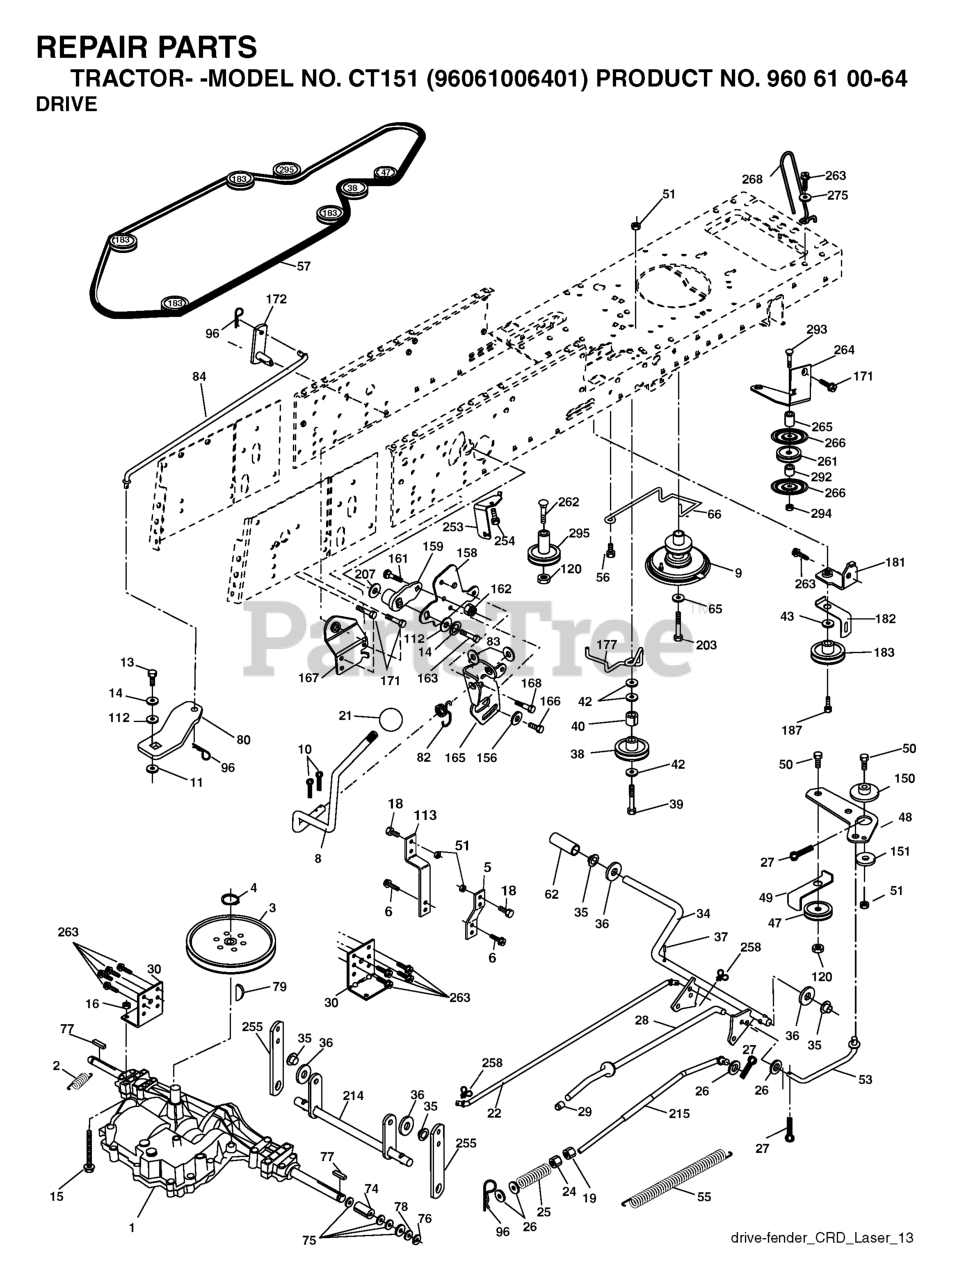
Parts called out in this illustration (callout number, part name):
2	SPRING,BRAKE RETURN
3	PULLEY
4	RETAINING RING LT
5	STRAP TORQUE
6	SCREW 5/16"
8	ROD SHIFT FENDER ADJUST LT
9	RP CLUTCH.NORAM.2002
10	PIN COTTER
11	WASH-SHFT PLT LT
13	BOLT 1/4-28X3/4
14	LOCKWASHER
15	BOLT HEX 5/16-18 GR 5
16	NUT.71038.31-18.HEX.NYLOCK
19	NUT
21	KNOB.DUCKHEAD.1/2
22	ROD
24	NUT
25	SPRING ROD LT
26	WASHER
27	COTTER PIN
28	ROD, PARKING BRAKE
29	PLUNGER CAP
30	BRKT, MOUNT TRNSAXLE
34	SHAFT, FOOT PEDAL
35	BEARING.NYLON
37	DRIVE PIN
38	PULLEY.FLAT
42	WASHER
47	IDLER PULLEY
48	BELLCRANK, CLUTCH
49	RETAIN BELT
50	BOLT.3/8-16X1.50
53	LINK.CLUTCH.7.66.2005
55	SPRING, RETURN LT
56	SCREW.3/8-16
57	V-BELT.KEV.111"
62	COVER, PEDAL (1 2)
65	LOCKWASHER
66	KEEPER BELT ENGINE
74	SPACER AXLE
77	SQUARE KEY
79	KEY STD (1373) DANA
82	SHIFT SPRING
83	WASHER
96	RETAINER M
120	NUT LOCK FLG 3/8-16 UNC
150	BUSHING.BELLCRANK.GRD.DR
151	WASHER 12/32X2X10GA
156	WASHER.SRRTD.5/16
158	BRACKET
159	RB HUB.SHIFT
161	BOLT
162	NUT.CROWNLOCK.1/4
165	RP BRACKET
166	CAPSCREW.HXHD.FLG.5/16-18X.625
167	BRACKET.SUPT.SHIFT.CRD
168	BOLT.SHOULDER.5/16-18X
172	SHAFT
181	BRACKET
182	BELT GUIDE
183	PULLEY.V-IDLER.GRND.DR
187	BOLT.5/16-18X1.25
203	BOLT.HEX.7/16-20 X 5
207	WASHER NYL
214	LEVER
254	SCREW 3/8-16X1
255	SHAFT
258	CLIP RETAINER
261	FLAT IDLER PULLEY
263	SCREW, 3/8-16X3/4
265	SPACER IDLER
266	PROTECTOR
268	GUARD MUFFLER
275	WASHER
292	SPACER
293	BOLT.RDHD SQNK 3/8-16 X 3-1/2
294	NUT.HEX.3/8-16
295	PULLEY IDLER COMPOSITE
